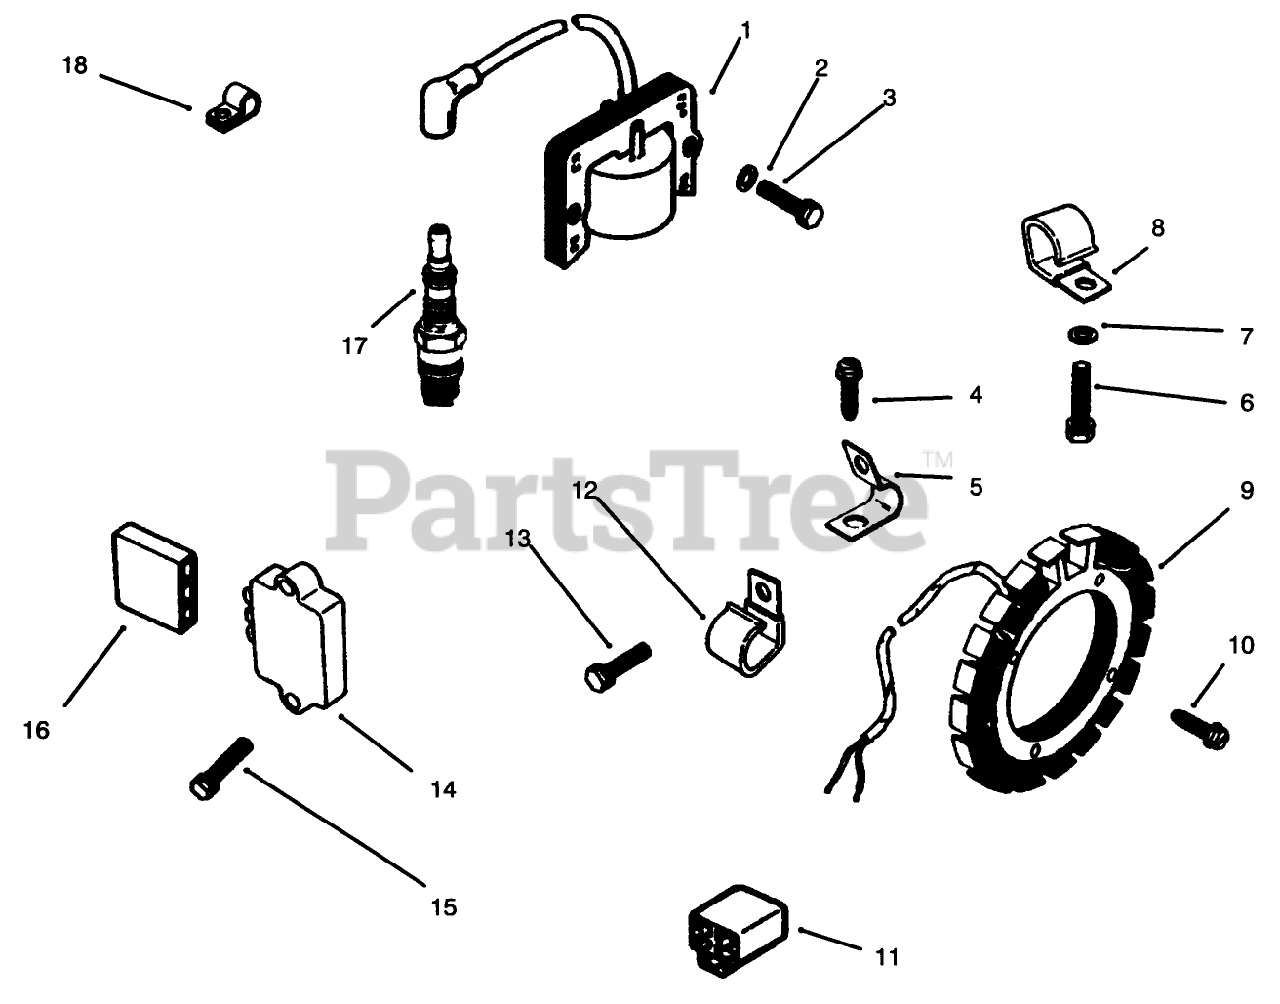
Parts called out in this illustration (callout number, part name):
1	Module-Ignition
2	Washer
3	Screw
4	Screw-Hex Hd
5	Clip
6	Screw
7	Washer
8	Clip
9	Stator
10	Screw
11	Connector
12	CLIP
13	SCREW-HH
14	Kit-Rectifier/Regulator (Incl. Ref. #2)
14	Regulator-Recifier
15	Screw
16	Connector
17	Plug-Spark
18	Clip-Cable
